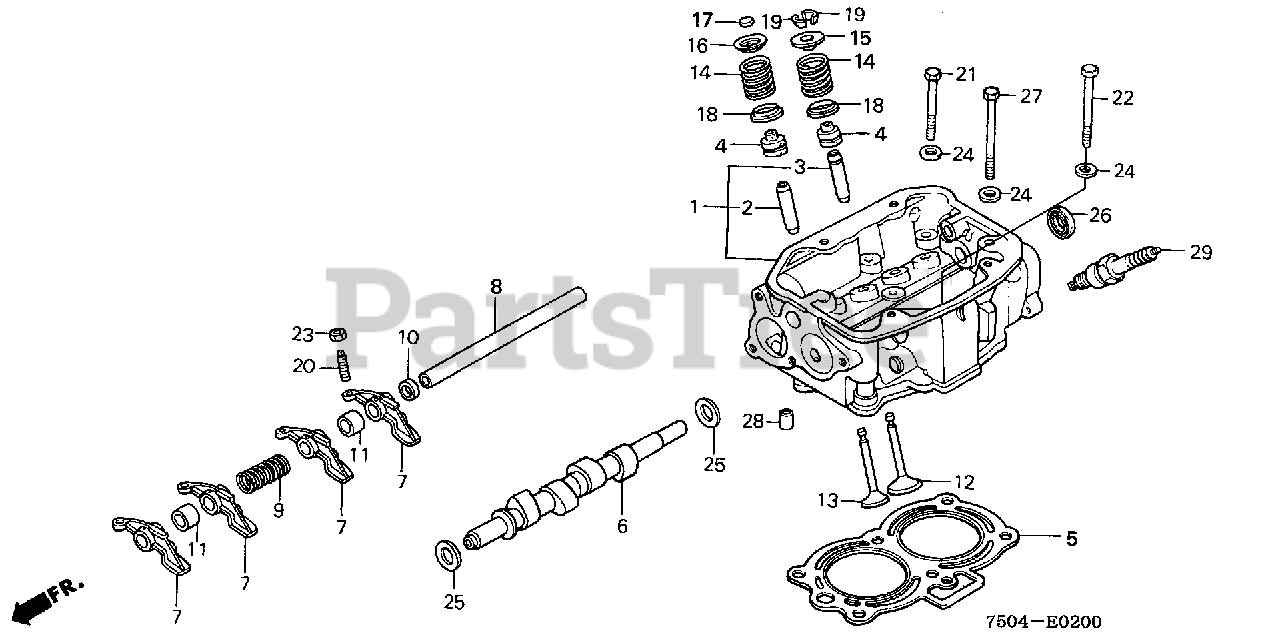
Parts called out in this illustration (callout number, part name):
1	CYLINDER HEAD
2	GUIDE, EX. VALVE Use up to Engine SN 1107750.
2	GUIDE, EX. VALVE
3	GUIDE, VALVE
3	GUIDE, VALVE (OS)
4	SEAL, VALVE STEM
5	GASKET, CYLINDER HEAD
6	CAM AND PULLEY KIT
6	CAMSHAFT
7	ARM, VALVE ROCKER
8	SHAFT, VALVE ROCKER ARM
9	SPRING, VALVE ROCKER ARM
10	COLLAR A, VALVE ROCKER ARM
11	COLLAR B, VALVE ROCKER ARM
12	VALVE, IN.
13	VALVE, EX.
14	SPRING, VALVE
15	RETAINER, VALVE SPRING
16	RETAINER, VALVE SPRING
17	ROTATOR, VALVE
18	SEAT, VALVE SPRING
19	COTTER, VALVE
20	SCREW, TAPPET ADJ.
21	BOLT, HEAD (8X70)
22	BOLT, HEX. (8X55)
23	NUT, TAPPET ADJ.
24	WASHER, HEAD (8MM)
25	WASHER, THRUST (16MM)
26	OIL SEAL (16X28X6)
27	BOLT, HEX. (8X100)
28	PIN A, DOWEL (10X16)
29	SPARK PLUG (BPR4HS) (NGK)
29	SPARK PLUG (BPR5HS) (NGK)
